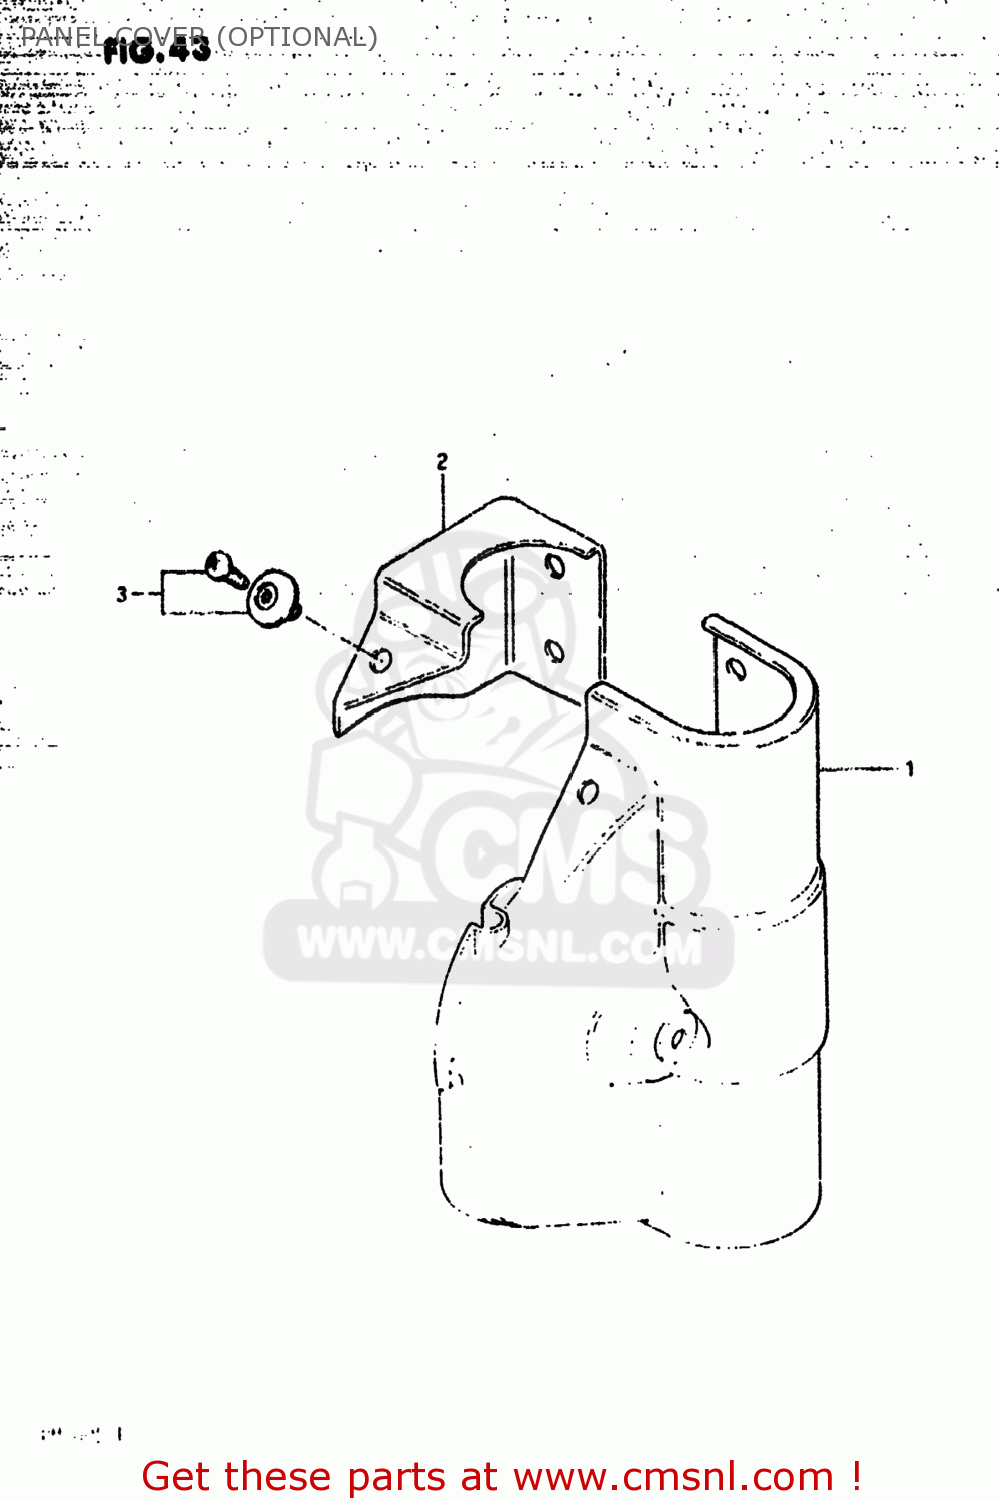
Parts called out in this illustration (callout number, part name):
1	COVER,FRONT HUB PANEL
2	CAP
3	CLIP(BLACK)
